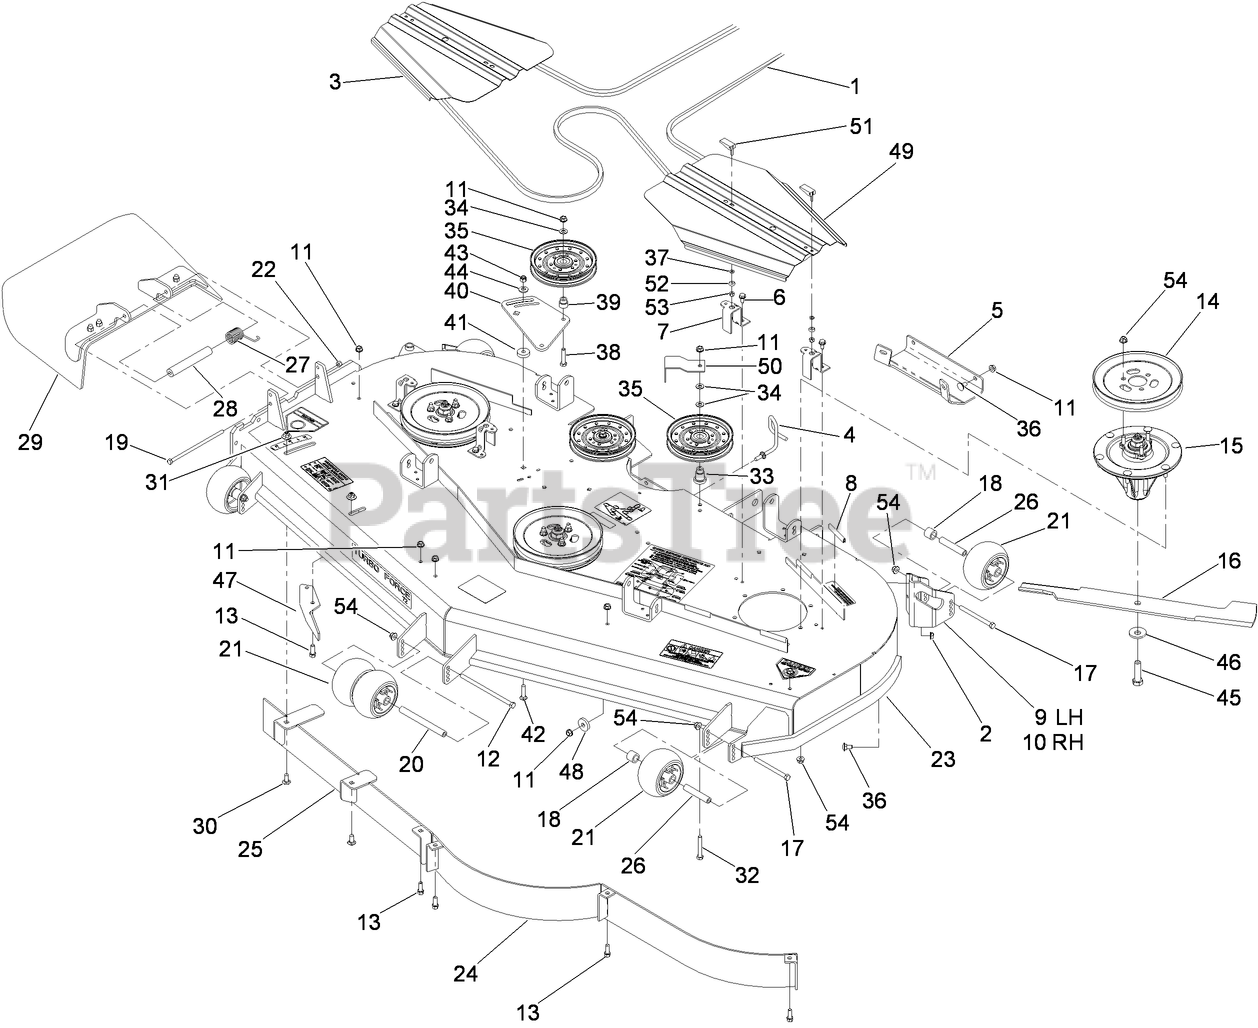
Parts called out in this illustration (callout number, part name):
2	NUT-LOCK, NI
3	COVER-BELT, RH
4	GUIDE-BELT
5	Plate-Skid
6	SCREW-HWHTF
7	BRACKET-COVER
8	STRIP-SEAL
9	MOUNT-WHEEL, LH
10	MOUNT-WHEEL, RH
11	NUT-HHF, WHIZ
12	SCREW-HH
13	SCREW-HWH
14	Pulley
15	SPINDLE ASM
16	BLADE-HI FLOW, 24.5 INCH
17	SCREW-HH
18	TUBE-SPACER
19	SCREW-HH
20	SPACER-WHEEL
21	ROLLER-SCALP, ANTI
22	NUT-LOCK, NI
23	DECK DECAL ASM
26	TUBE-SPANNER
27	SPRING-TORSION
28	SPACER
29	RUBBER DEFLECTOR ASM
30	SCREW-CARR
31	NUT-FLANGE, NI
32	SCREW-HH
33	MOUNT-PULLEY
34	WASHER-FLAT
35	Idler-Flat
36	SCREW-CARR
37	WASHER
38	SCREW-HH
39	BUSHING-IDLER
40	Plate-Idler
41	Spacer
42	SCREW-CARR
43	NUT-LOCK, NI
44	WASHER-BELLEVILLE
45	SCREW-BLADE
46	Washer-Blade Bolt, Heavy
47	BAFFLE-DISCHARGE
48	WASHER
49	COVER-BELT, LH
50	GUIDE-BELT
51	HANDLE-LATCH, SWELL
52	BUSHING-LATCH, SWELL
53	NUT-LOCK, HH
54	NUT-HF, NI
